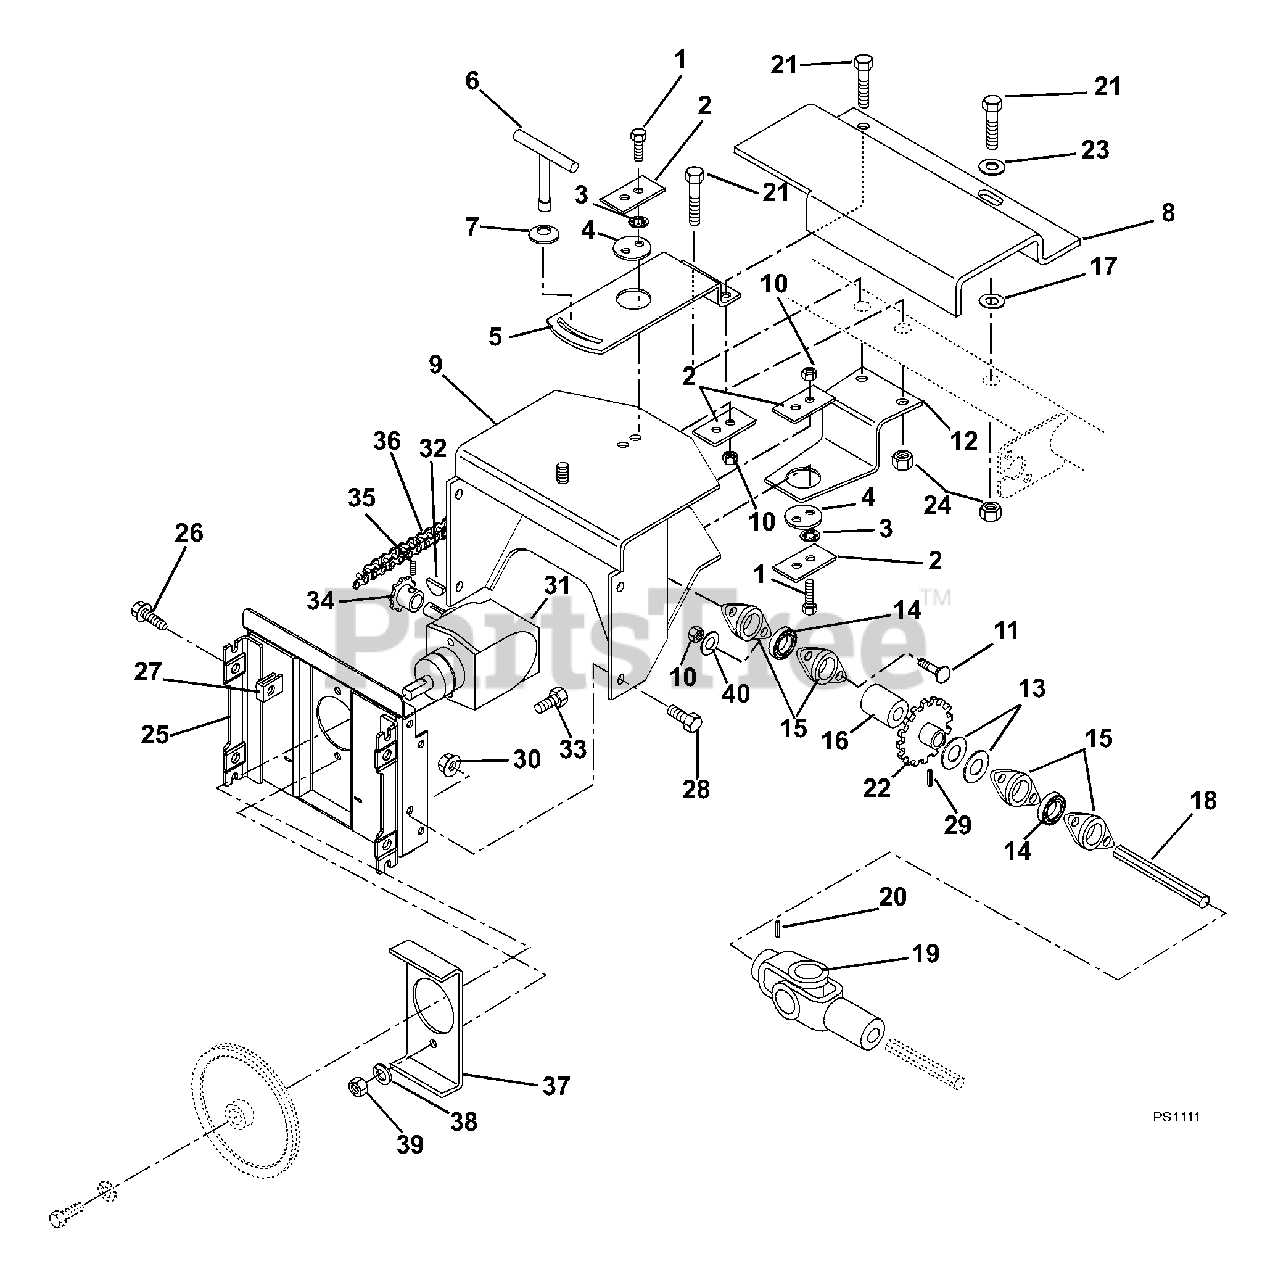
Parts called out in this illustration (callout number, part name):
1	@BLT-HEX .31-18X1.25 GR5 YWZC
2	RETAINER
3	@WSHR-LK-EXT.326X.599X.031YWZC
4	PIVOT CENTER
5	PLATE, TOP MOUNT
6	T-LOCK HANDLE
7	WSHR-BLVL .669X1.535X.138
8	GUARD, SHAFT
9	FRAME, ADAPTOR
10	@NUT-LK-CTR .31-18 YWZC
11	@BLT-RDHDSQNK .31-18X.75 G5YZ
12	PLATE, BOTTOM MOUNT
13	WSHR-FL-STL 1.015X1.500X.125
14	BRG-BALL .884HEXX52MMX1.07
15	BEARING FLANGE
16	SPACER 1.006X1.307X.500
17	WSHR-FL-STL .390X.88X.18 YWZC
19	JOINT, UNIVERSAL
20	PIN-ROLL .188X1.50
21	@BLT-HEX .38-16X3.25 GR5 YWZC
22	SPROCKET
23	@WSHR-FL-STL.406X.812X.065 YWZ
24	@NUT-LK-CTR .38-16 YWZC
25	PLATE, MOUNTING-BROOM
26	BLT-SERHFWH .38-16X.75 YWZC
27	NUT-RETNR .38-16 TINRMAN
28	@BLT-HEX .38-16X.75 GR5 YWZC
29	PIN-ROLL .188X1.75
30	@NUT-LK-CTR .38-16 YWZC
31	GEAR BOX ASSEMBLY
32	KEY-WDRF .188X.75X.313 SAE 9
33	@BLT-HEX .38-16X1.25 GR5 YWZC
34	SPROCKET
35	SCR-SET .25-20X.38 SKHCUPNL OH
36	ROLLER CHAIN #41 - 34 PITCHES
37	PLATE, STIFFENER
38	@WSHR-LK .38X.094 REG YWZC
39	@NUT-HEX .38-16 YWZC
40	@WSHR-FL-STL.38X.875X.083 YWZC
